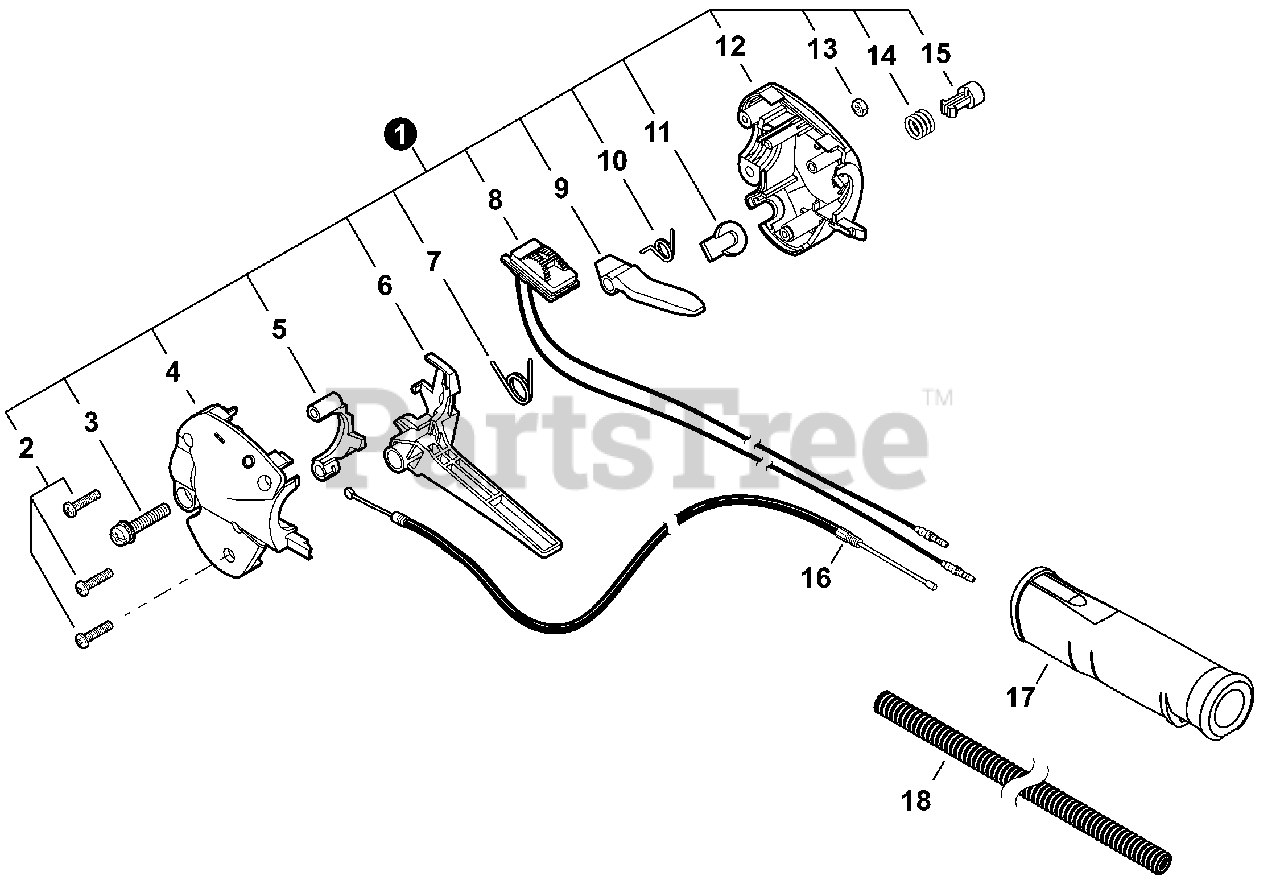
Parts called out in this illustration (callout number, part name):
1	THROTTLE CONTROL ASSY
2	SCREW, TAPPING M4x20
3	SCREW M5x20
4	CONTROL HANDLE - LEFT
5	LOCKOUT, THROTTLE
6	TRIGGER, THROTTLE
7	SPRING, THROTTLE RETURN
8	SWITCH, ON-OFF
9	LEVER, THROTTLE LOCKOUT
10	SPRING, THROTTLE LOCKOUT
12	CONTROL HANDLE - RIGHT
14	SPRING, COMPRESSION
15	BUTTON, THROTTLE LOCK
16	CABLE, THROTTLE
17	GRIP, REAR
18	TUBE, PLASTIC PROTECTIVE
